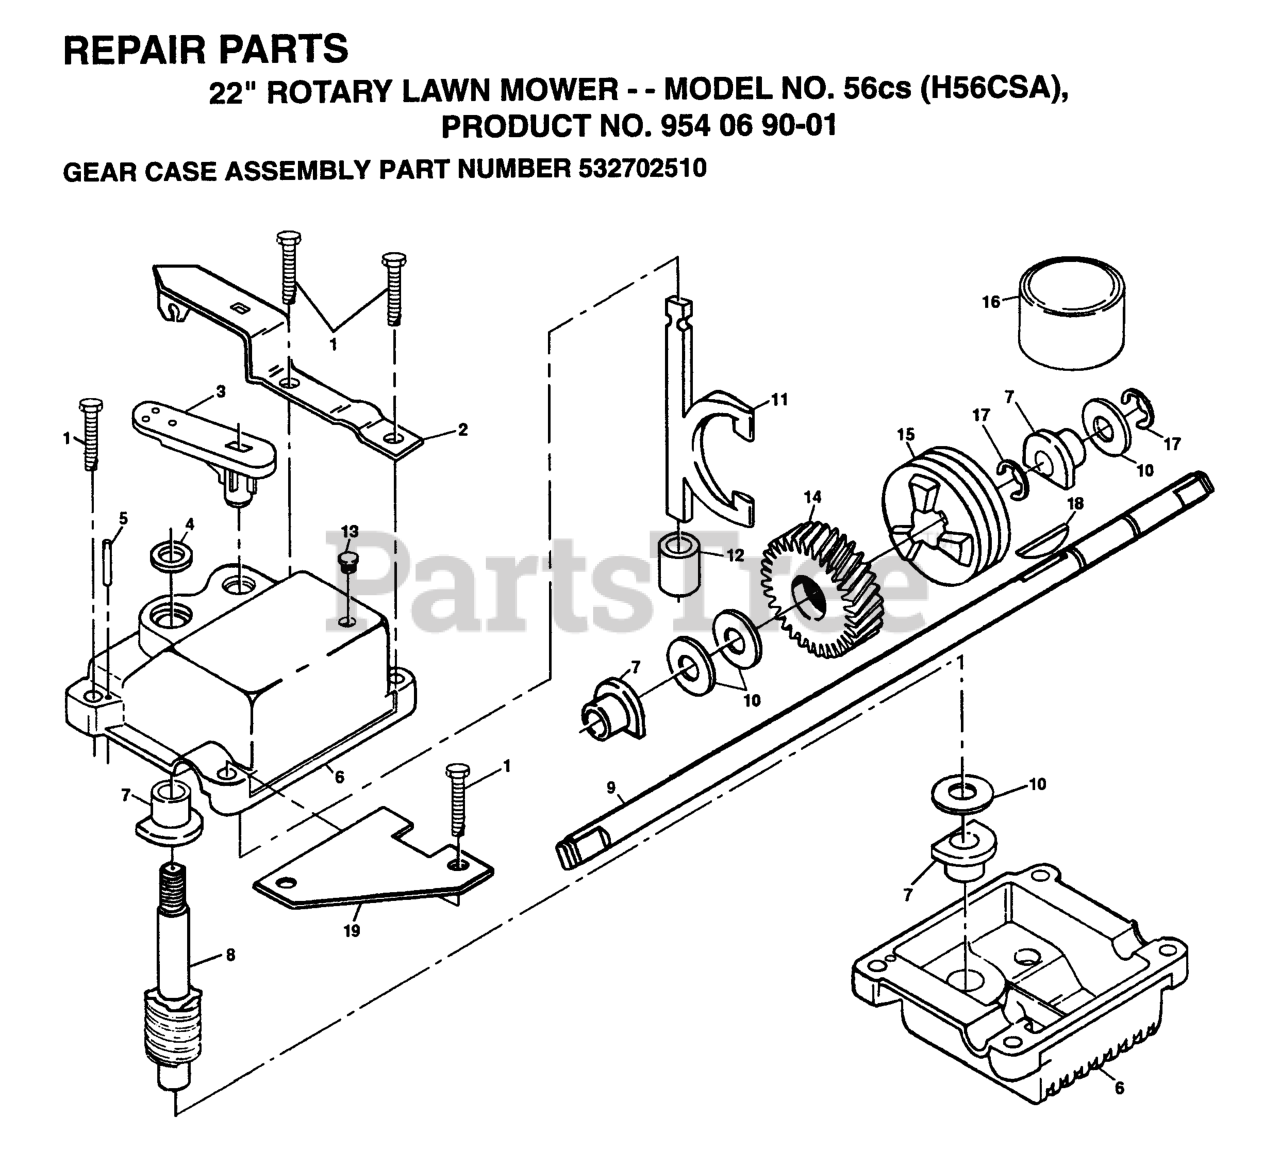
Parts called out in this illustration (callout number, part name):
1	SCREW
2	BRACKET
5	GROOVED PIN
8	WORM SHAFT
9	DRIVE SHAFT, 21-1/16"
10	THRUST WASHER
11	YOKE.VIBRATORY FINISH.
13	PLUG.AUGER.GEAR.BOX.SNOW
14	GEAR.HELICAL
15	CLUTCH JAW
16	GREASE
18	HI PRO KEY
19	BRACKET SPRING
